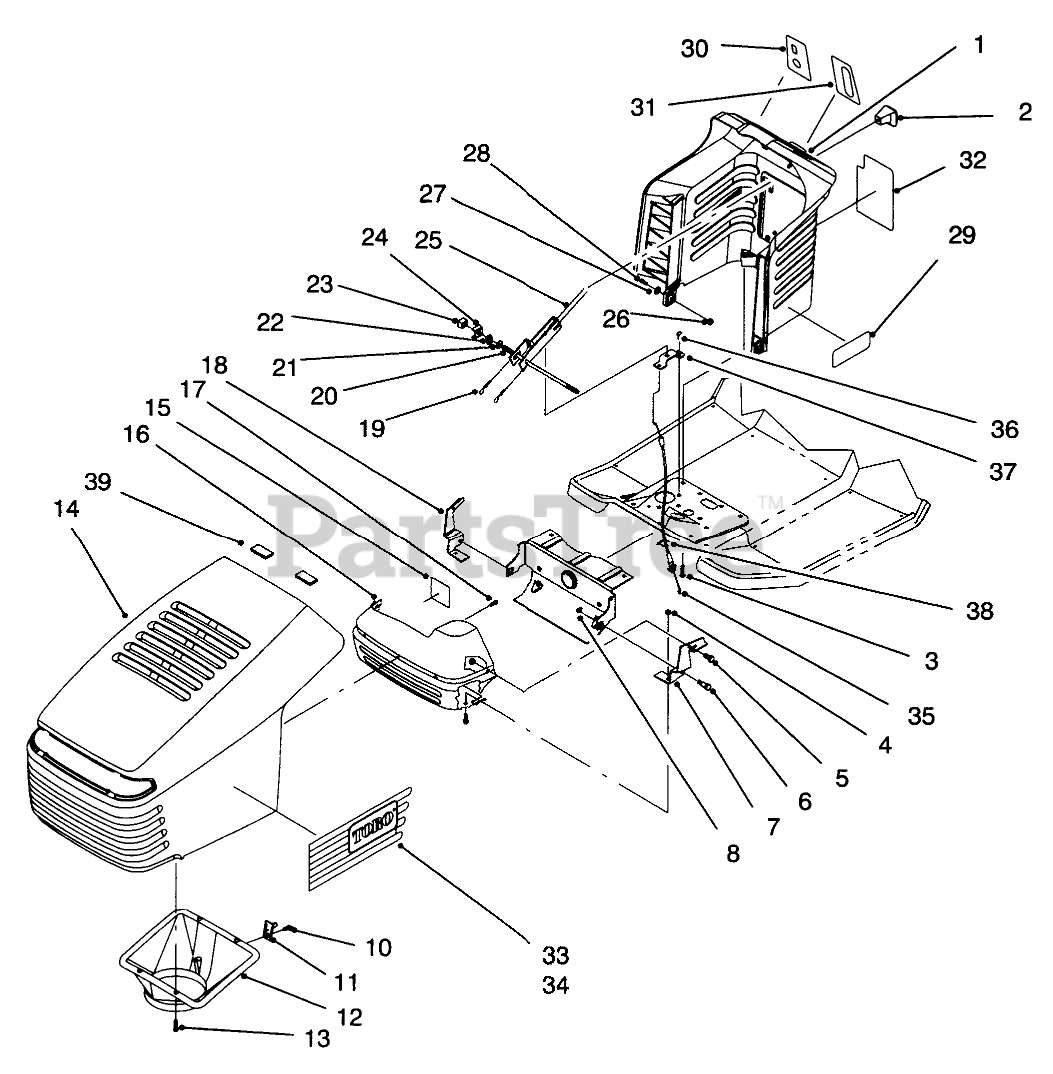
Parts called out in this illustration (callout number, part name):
1	Tower-Steering
2	KNOB-SHIFT
3	SCREW-HWH
4	NUT-LOCK, NI
5	SCREW-HH
6	BOLT-SHOULDER
7	Bracket-Hinge L.H.
8	NUT-RETAINER
10	SCREW-HWH
11	LATCH-PIN
12	DUCT-AIR, HOOD
13	SCREW-PLASTITE
14	HOOD ASM
15	TAPE-FOIL
16	Shield-Heat
17	SCREW-PLASTITE
18	Bracket-Hinge R.H.
19	PIN-COTTER
20	ROD-TOWER PIVOT
21	WASHER-FLAT
22	NUT-FLANGE
23	NUT-WEDGE
24	ROD-CLAMP PIVOT
25	Lever-Deck Engage
26	NUT-LOCK, NI
27	WASHER-PLAIN
28	SCREW-HH
29	DECAL-TOWER 1644 HXL
30	DECAL-IGNITION/LIGHTS
31	DECAL
32	DECAL-DECK, ENGAGE
33	DECAL - HOOD LEFT
34	DECAL - HOOD RIGHT
35	Cable-Deck Engage
36	SCREW-HWH
37	BRACKET-CABLE, UPPER
38	TIE-CABLE
39	FOAM-HOOD
